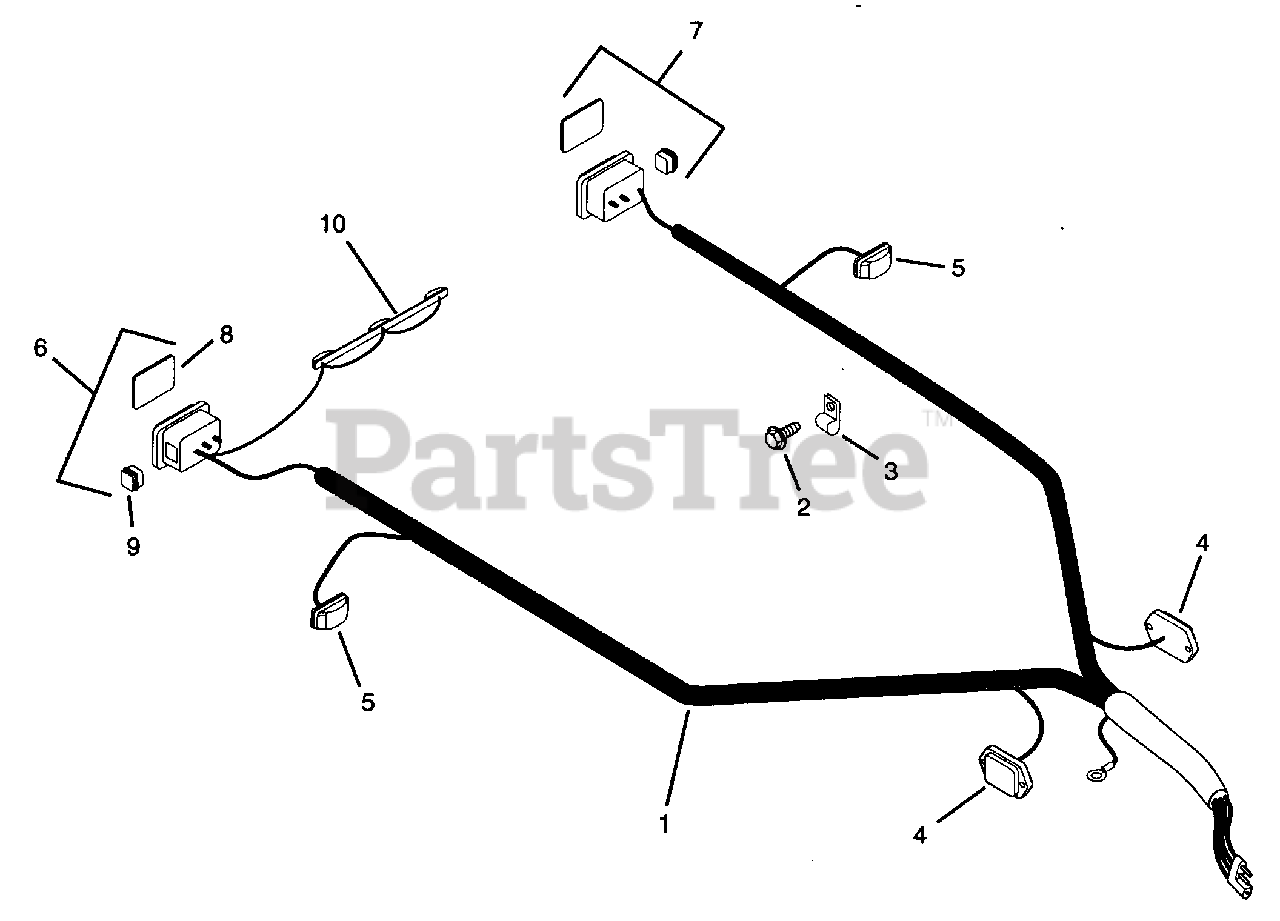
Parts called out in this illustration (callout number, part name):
1	Wiring Harness - 495 Lights
2	Screw-Tapping 10-16 x .75 Hex Washer Head
3	Clamp-Tubing
4	Light-Side Marker, Ear Mount
5	Light-Amber, Stud Mount
6	Tail Light-Right Hand
7	Tail Light-Left Hand
8	Lens-Tail Light Replacement
9	Lens-S/M Replacement
10	Light Bar-ID Bar
